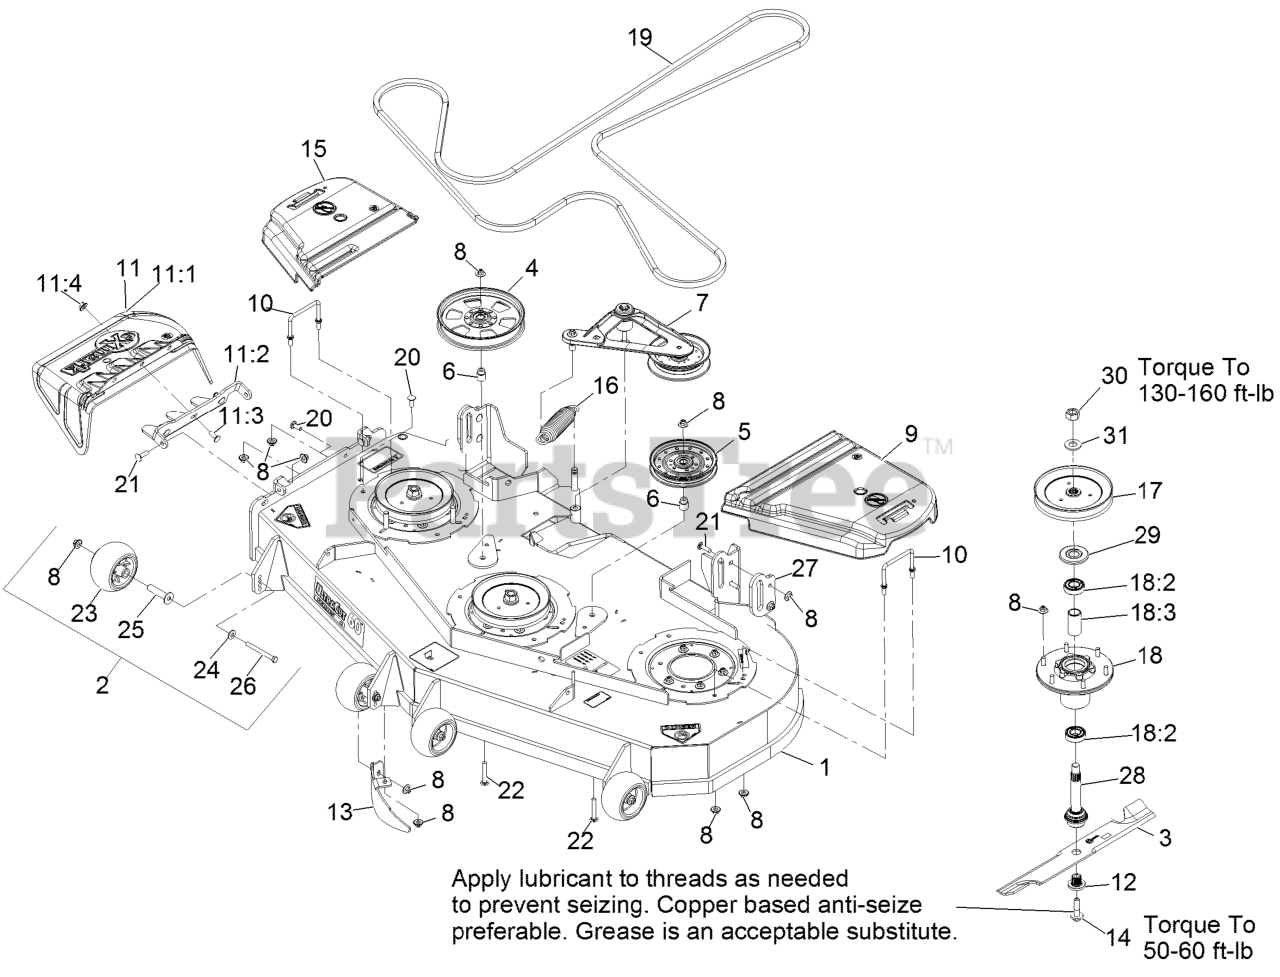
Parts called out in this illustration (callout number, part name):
1	DECK ASM, W/DECALS 604
2	KIT, ANTI-SCALP ROLLER
3	Blade-Extreme 2, 20.50"
4	PULLEY-IDLER, FLAT
6	BUSHING-IDLER
7	DECK IDLER ASM
8	Nut-Nyloc 3/8-16 Flg
9	COVER-BELT, LH
10	WIREFORM-COVER
11	ASM,DISCHARGE CHUTE
11:1	CHUTE,DISCHARGE
11:2	BRACKET,DISCHARGE CHUTE
11:3	SCREW-CARR
11:4	Nut-Nyloc 3/8-16 Flg
12	BUSHING,SPLINED
13	DOGLEG - LZ60
14	SCREW,SEMS 1/2-20 X 2.19
15	COVER-BELT, RH
16	SPRING-EXTENSION
17	SHEAVE,BLADE DRIVE 7.25
18	ASM-CUTTER HSG WITH BEARINGS
18:2	BEARING-BALL
18:3	SPACER-BEARING
19	BELT,V-5V-198.75
20	SCREW-CARR
21	Bolt-Carriage 3/8-16 X 1 1/4
22	SCREW-CARR
23	ROLLER-SCALP, ANTI
24	WASHER-BELLEVILLE
25	AXLE, ROLLER
26	SCREW-HH 3/8-16 X 3 3/4 GR 8
27	PLATE-REINF, PUSH TOWER
28	ASM-SPINDLE AND SEAL
29	GUARD,BEARING TOP .989
30	NUT-HEX
